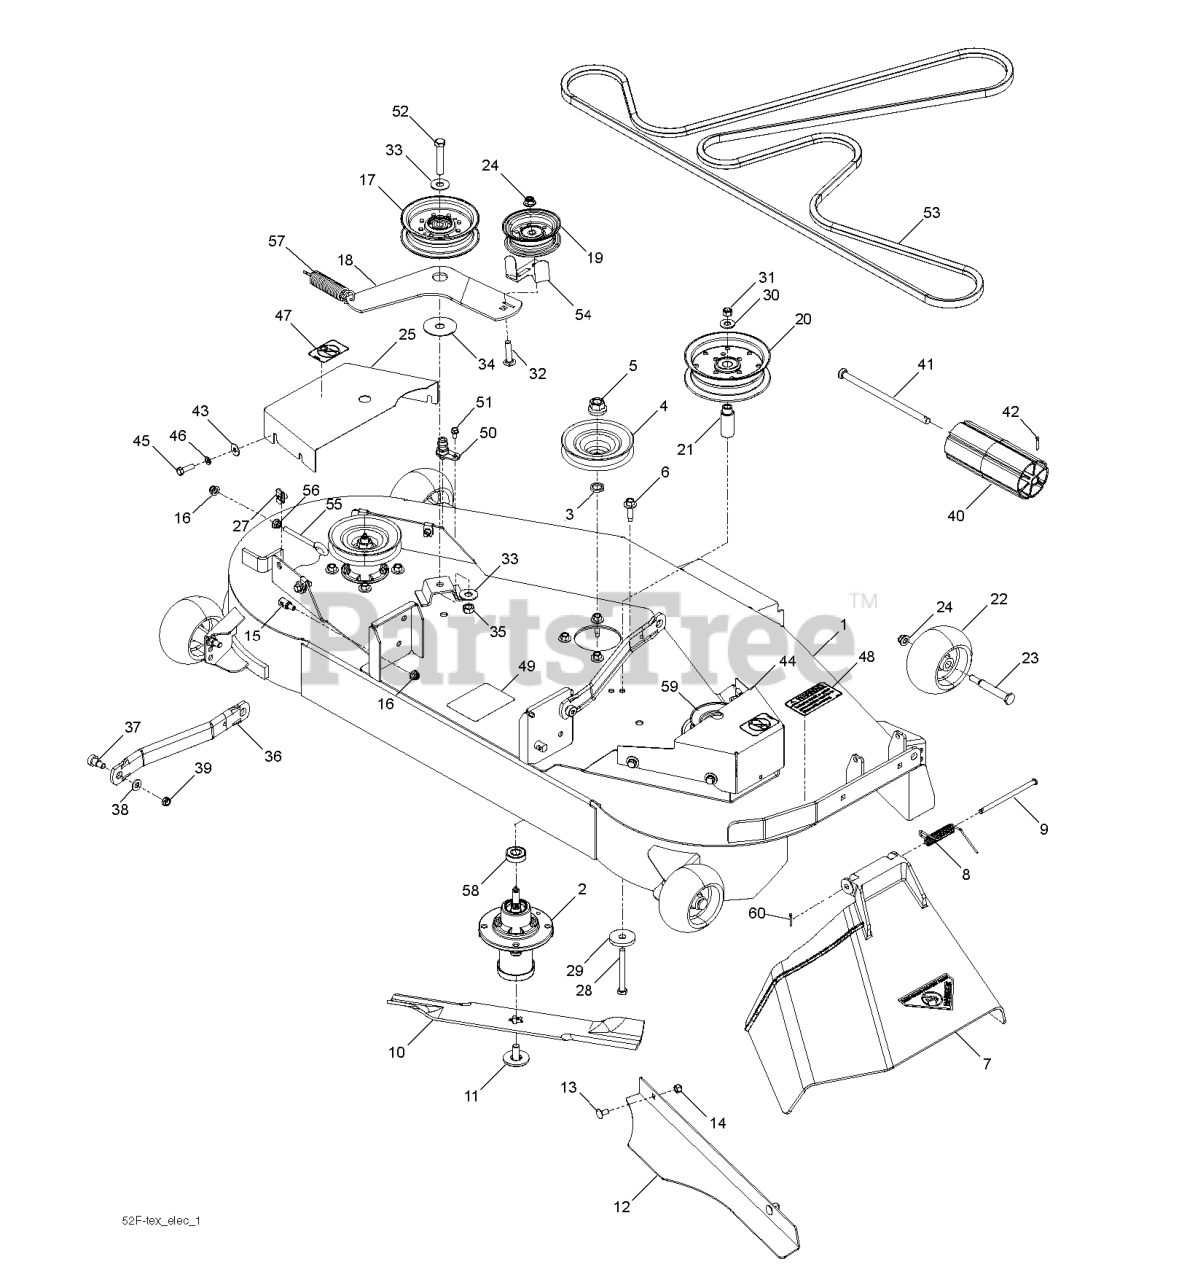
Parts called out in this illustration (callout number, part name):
1	THROTTLE HANDLE ASSY
2	HANDLE HALF LEFT
3	LOCKOUT STARTER THROTTLE
5	THROTTLE CONTROL
9	HANDLE HALF RIGHT
10	SCREW
12	STOP BUTTON
14	NUT M6M M5
17	SCREW 6X70
19	HANDLEBAR BRACKET KIT
24	WIRING ASSY
25	SCREW
